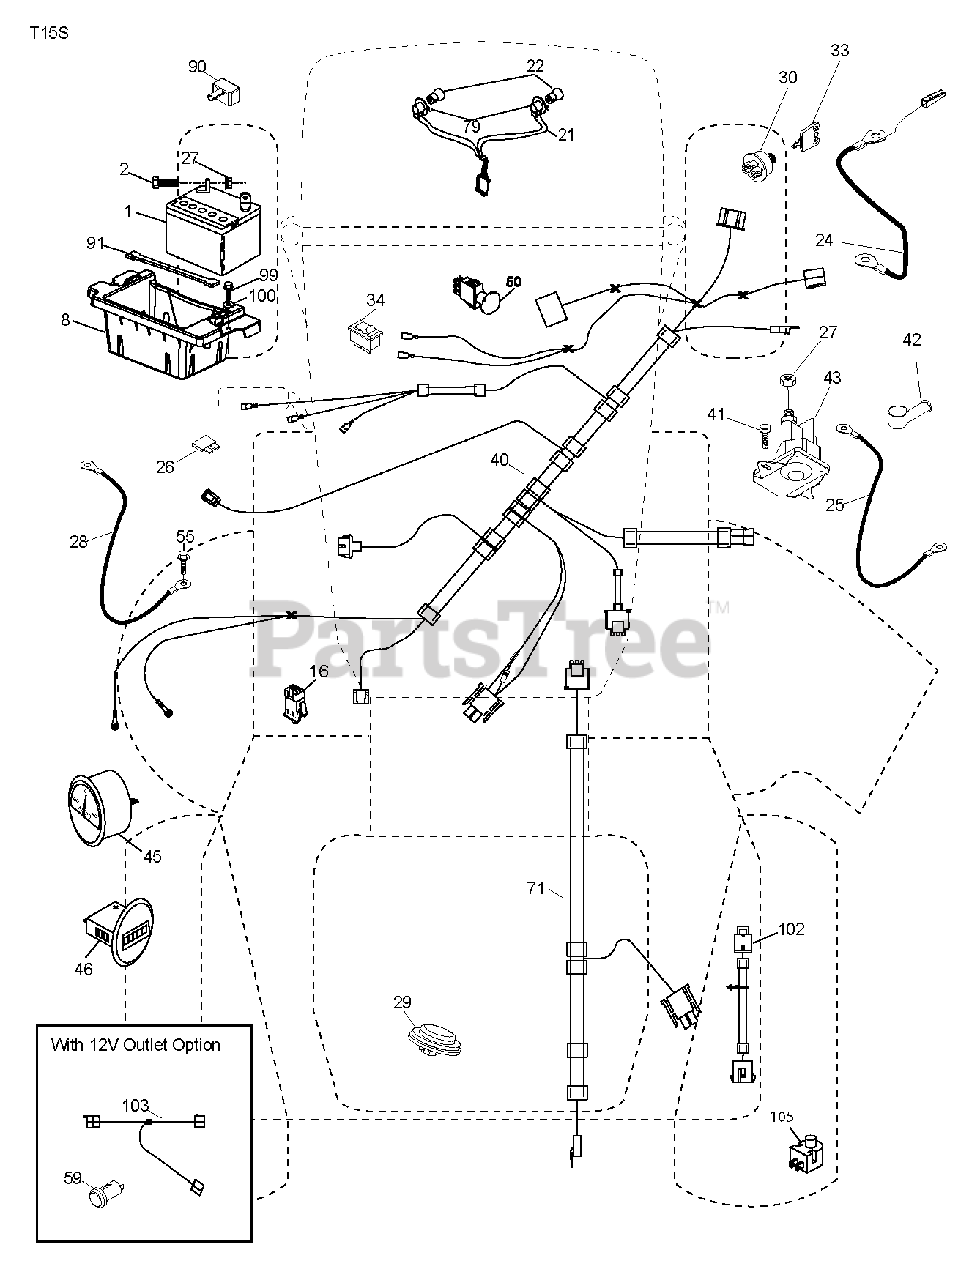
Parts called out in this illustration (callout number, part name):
2	BOLT LT
8	BOX, BATTERY MOUNT
16	SWITCH INTERLOOK PUSH-IN
21	HARNESS SOCKET LIGHT
22	LIGHTBULB
24	CABLE.BTRY.PSWRE.DSH.S
25	CABLE.STARTER.6G.BL/RED.17.5
26	FUSE 20AMP
28	CABLE GROUND 6 GA 21" 90T BLK
29	SWITCH.SEAT.DELTA.OPC.
30	IGNITION SWITCH
33	KEY/CHAIN.BLISTER.PACK.GEN.USA
34	SWITCH LT
40	HARNESS IGN. DASH
43	SOLENOID.W/BRASS.PLUNG
45	AMMETER.ROUND.SNAPIN
46	HOURMETER.ROUND.SNAPIN
50	PTO SWITCH
71	HARNESS-CHASSIS SUB
79	BULB HOLDER ASM.
91	STRAP, BATTERY MOUNT
99	SCREW HEXWSHR 1/4-20X3/4
102	HARNESS PIGTAIL PCH TEX ROS
105	REVERSE SWITCH
